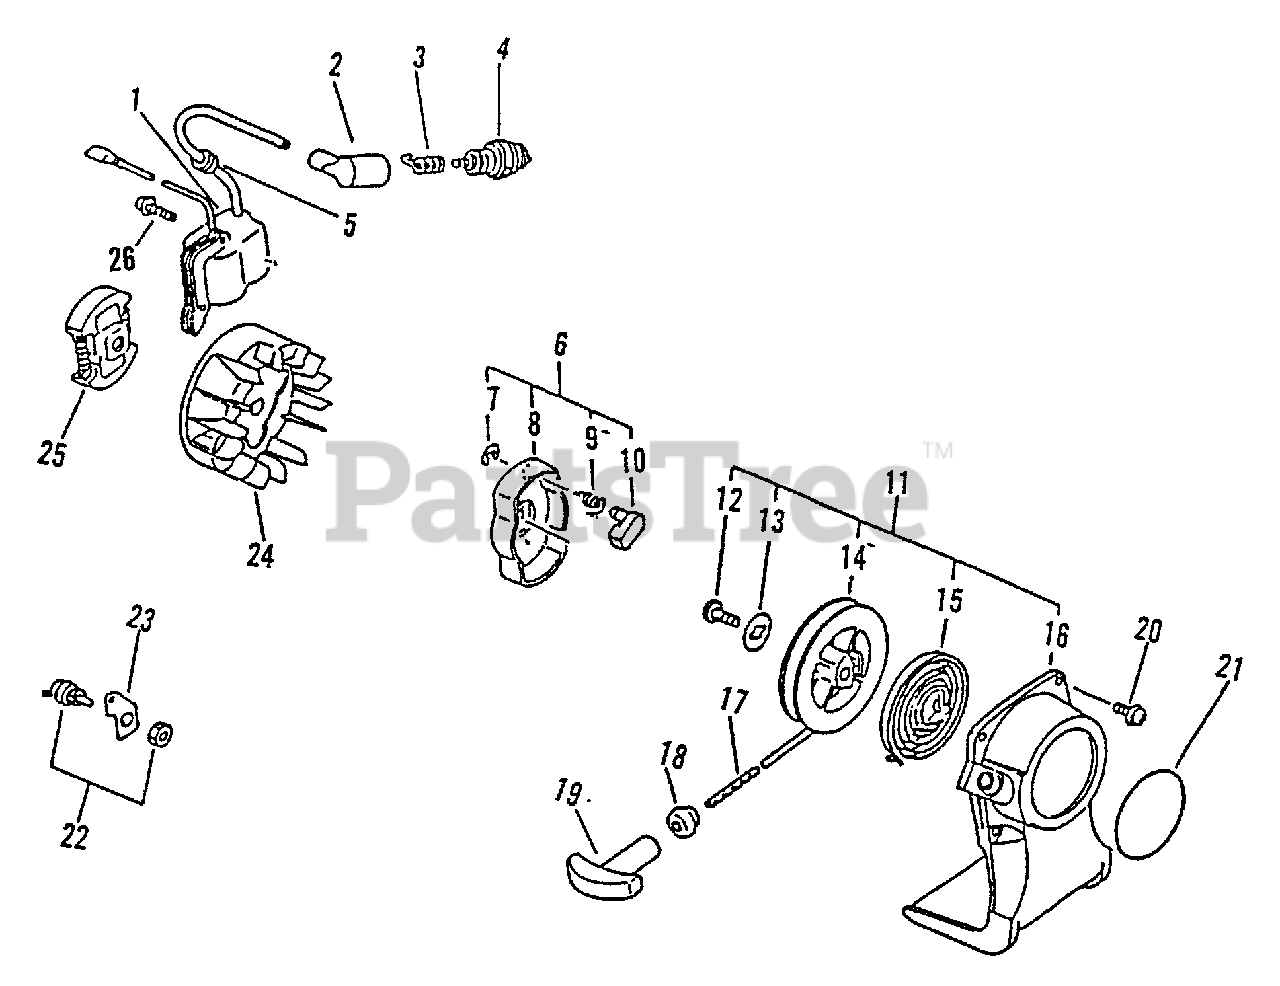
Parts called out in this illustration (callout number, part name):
1	COIL, IGNITION
2	CAP, SPARK PLUG
3	TERMINAL, SPARK PLUG CAP
4	SPARK PLUG -- BPM-7A
4	SPARK PLUG -- BPMR-7A
5	GROMMET
6	STARTER PAWL ASSY
7	RING, RETAINING - 4
8	CATCHER, PAWL
9	SPRING, RETURN
10	PAWL, STARTER
11	STARTER ASSY
13	WASHER
14	REEL, ROPE
15	SPRING, REWIND
16	CASE, STARTER - BLUE
17	ROPE, STARTER - 3X890
18	GUIDE, ROPE
19	GRIP, STARTER
20	SCREW - 4X16
21	LABEL - ECHO
22	IGNITION SWITCH ASSY
23	BRACKET, SWITCH
24	FLYWHEEL
25	CLUTCH ASSY
26	SCREW - 4X22
